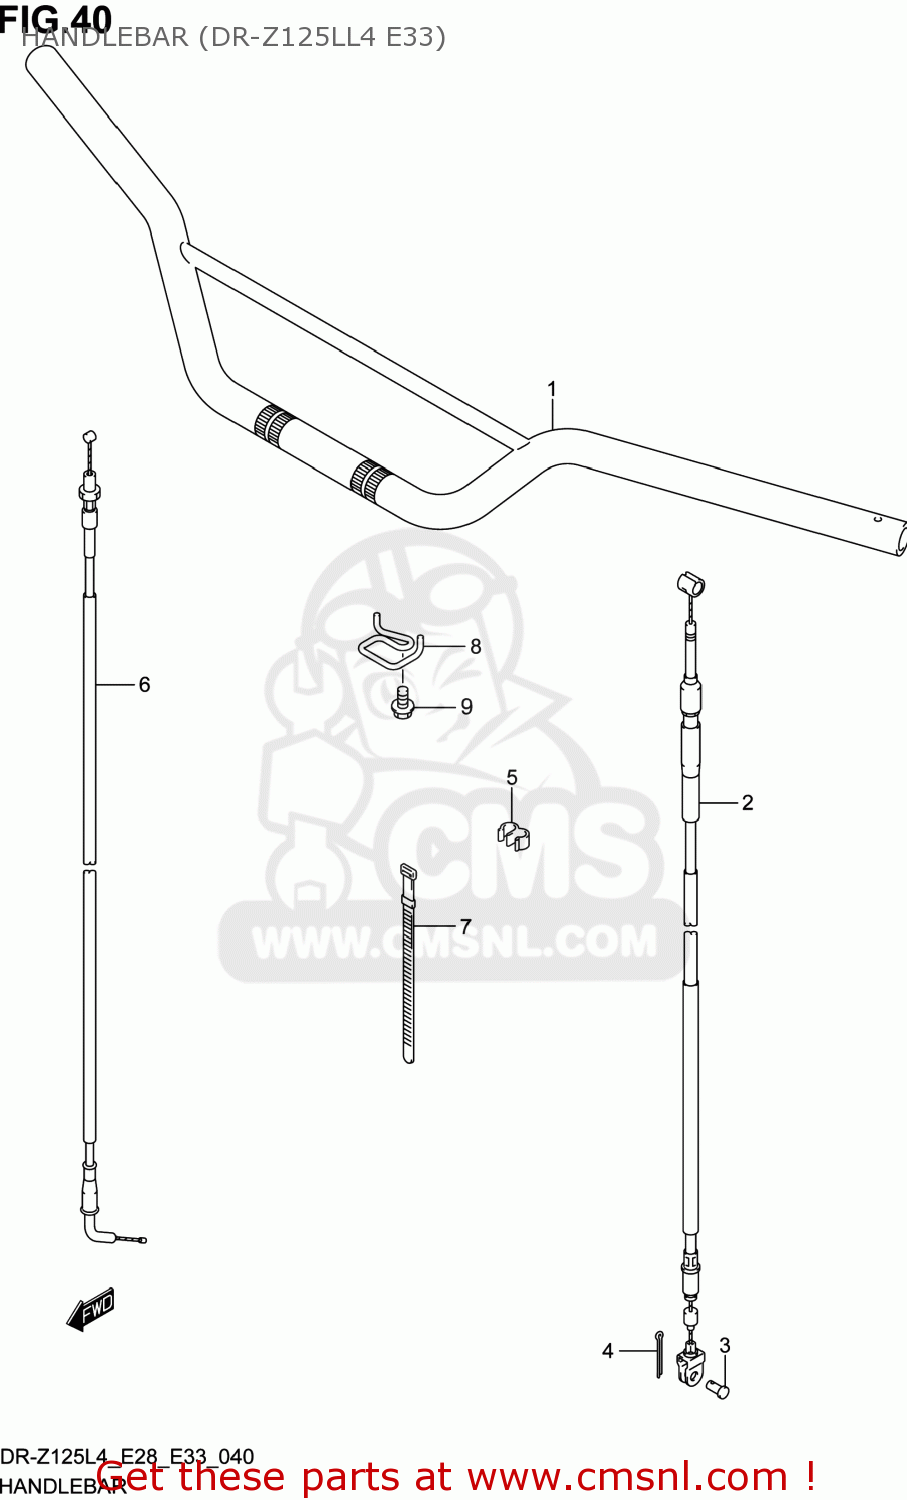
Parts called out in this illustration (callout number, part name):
1	HANDLEBAR(SILVER)
2	CABLE ASSY,CLUTCH
3	PIN(L:13)
4	PIN
5	CLAMP
6	CABLE ASSY,THROTTLE
7	CLAMP(L:90)
8	GUIDE,CABLE
9	BOLT
